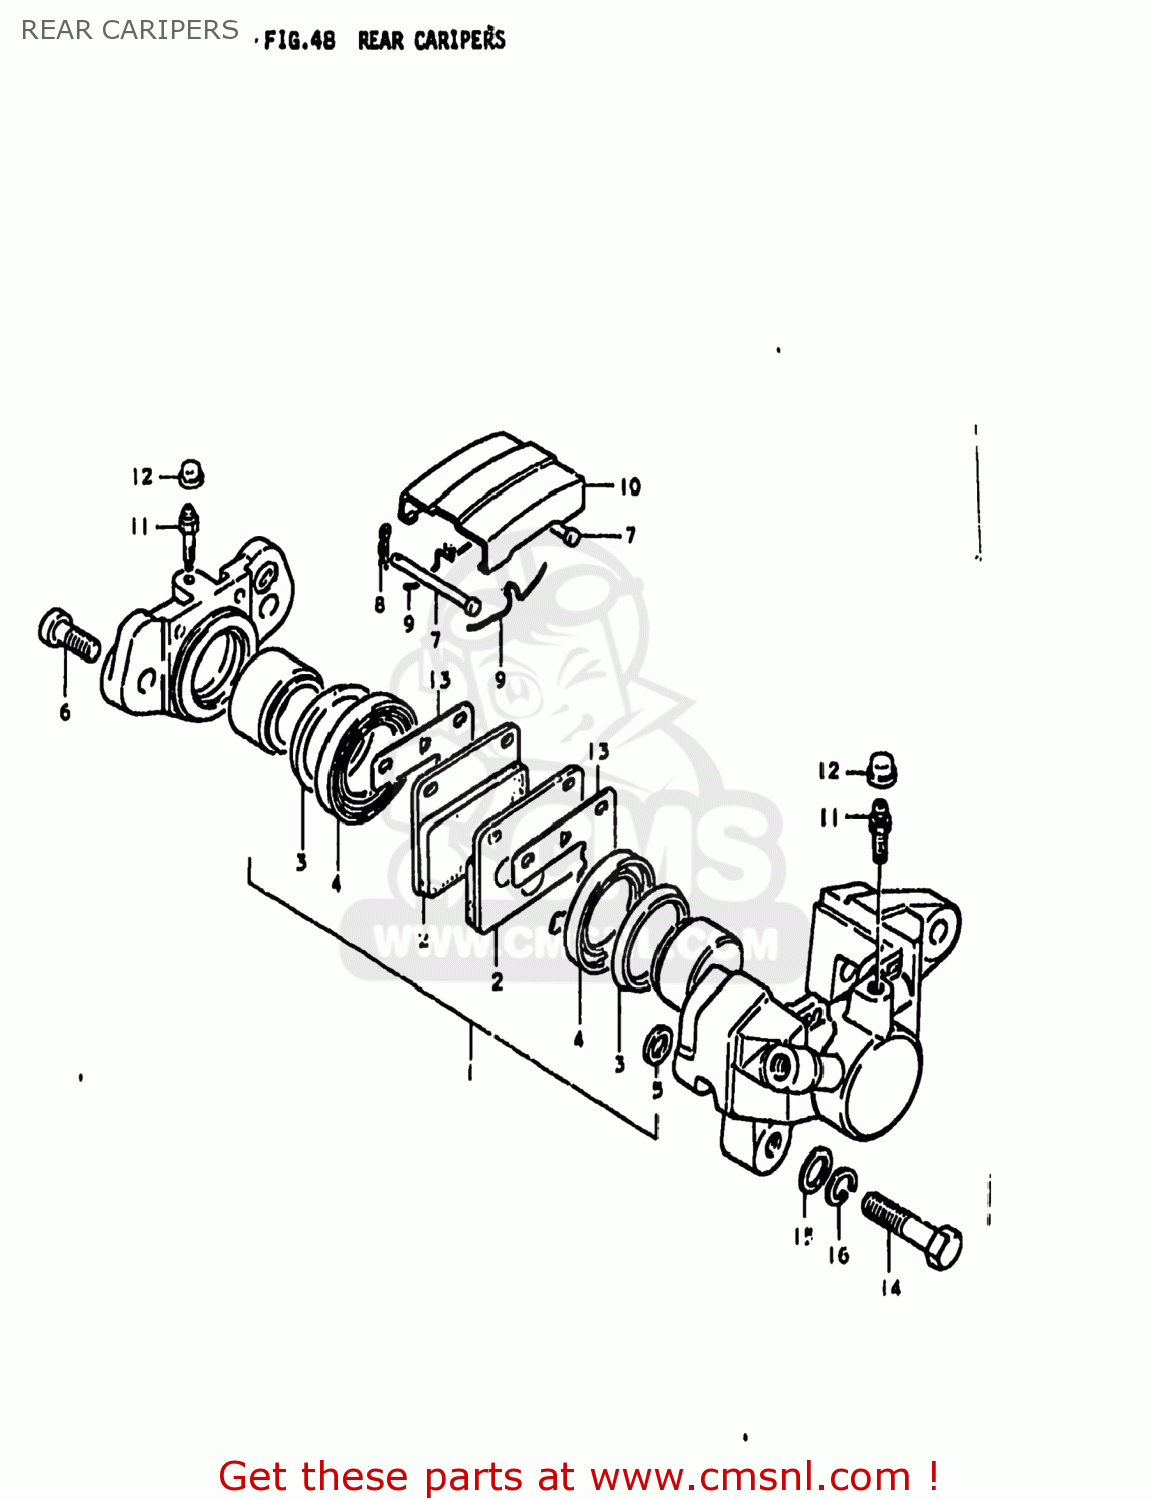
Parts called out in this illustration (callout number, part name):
1	PISTON SET
2	PAD,BRAKE
3	SEAL,PISTON
4	BOOT,PISTON
5	SEAL,PISTON
6	BOLT,HOUSING
7	PIN,PAD
8	CLIP,PAD PIN
9	SPRING
10	COVER,DUST
11	BLEEDER
12	CAP,BREATHER
13	SHIM,RR CALIPER
14	BOLT 10X34
15	WASHER
16	LOCK WASHER
